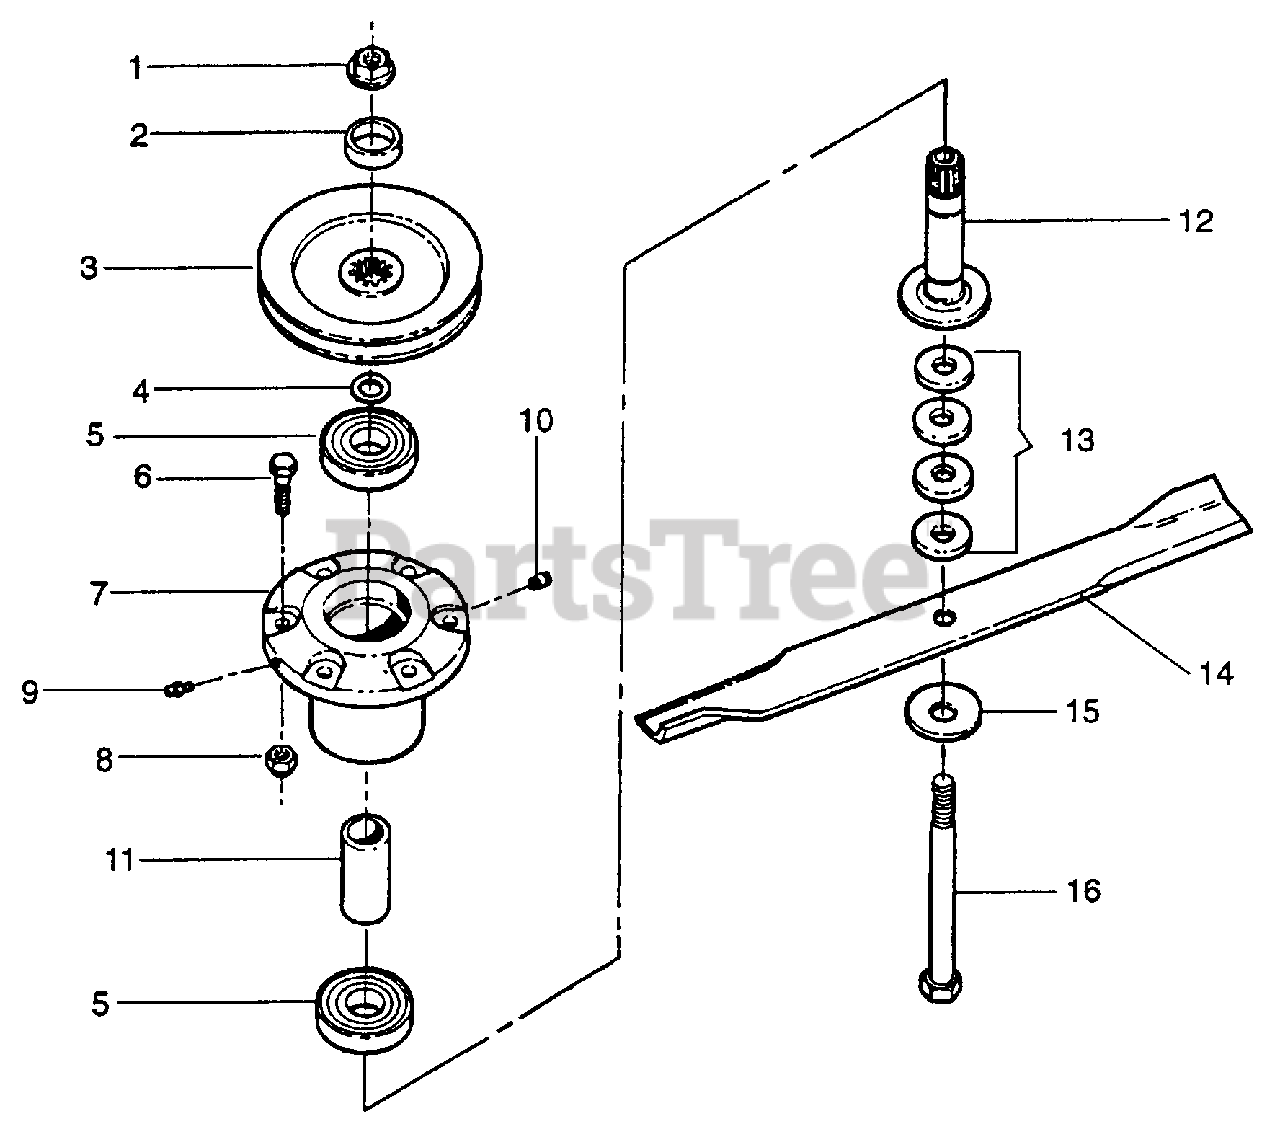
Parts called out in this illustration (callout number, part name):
1	NUT, 5/8- 18 Hex Flange Lock, Grade 5
2	WASHER, Spindle
3	PULLEY, 5-3/4" O.D.
4	SNAP RING, Spindle Shaft
5	BEARING, Sealed
6	BOLT, 3/8 - 16 x 1-1/4" Rib Necked
7	HOUSING, Cutter
8	NUT, 3/8-16 HEX NYLON LOCK
9	LUBE FITTING, 1/4-28 Thread Forming
10	VENT, Spindle
11	SPACER, Bearing
12	SHAFT, Spindle
13	SPACER, Blade
14	BLADE, 25 Inch
15	WASHER, Beveled
16	BOLT, 5/8 - 7-1/2" Hex Head Cap, Grade 5
